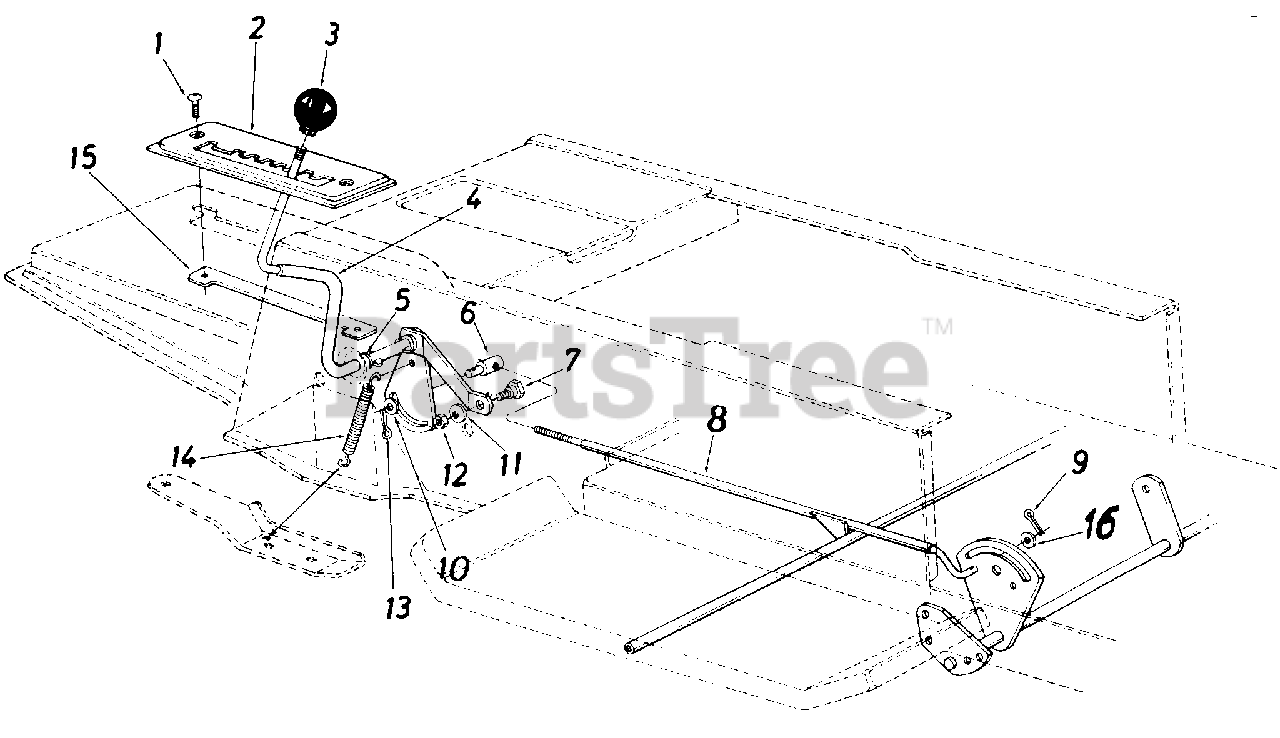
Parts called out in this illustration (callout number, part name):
1	Truss Mach. Scr. 1/4-20 x .75" Lg.
2	Speed Selector Plate 4-Speed
4	Speed Selector Cam Ass'y.
5	Flat Washer .53" I.D. x .93" O.D.
6	Ferrule 3/8-24 x .37" Dia.
7	Shoulder Bolt .435" Dia. x .160
8	Speed Control Rod Ass'y.
9	Cotter Pin 3/32" Dia. x .75" Lg.
10	Fl-Wash..39" I.D.
11	L-Wash. 5/16" I.D.*
12	Hex Nut 5/16-18 Thd.*
13	Hairpin Cotter 1/8" Dia.
14	Spring
15	Clamping Plate
16	Fl-Wash. .47" I.D. x .88 O.D. x .063
